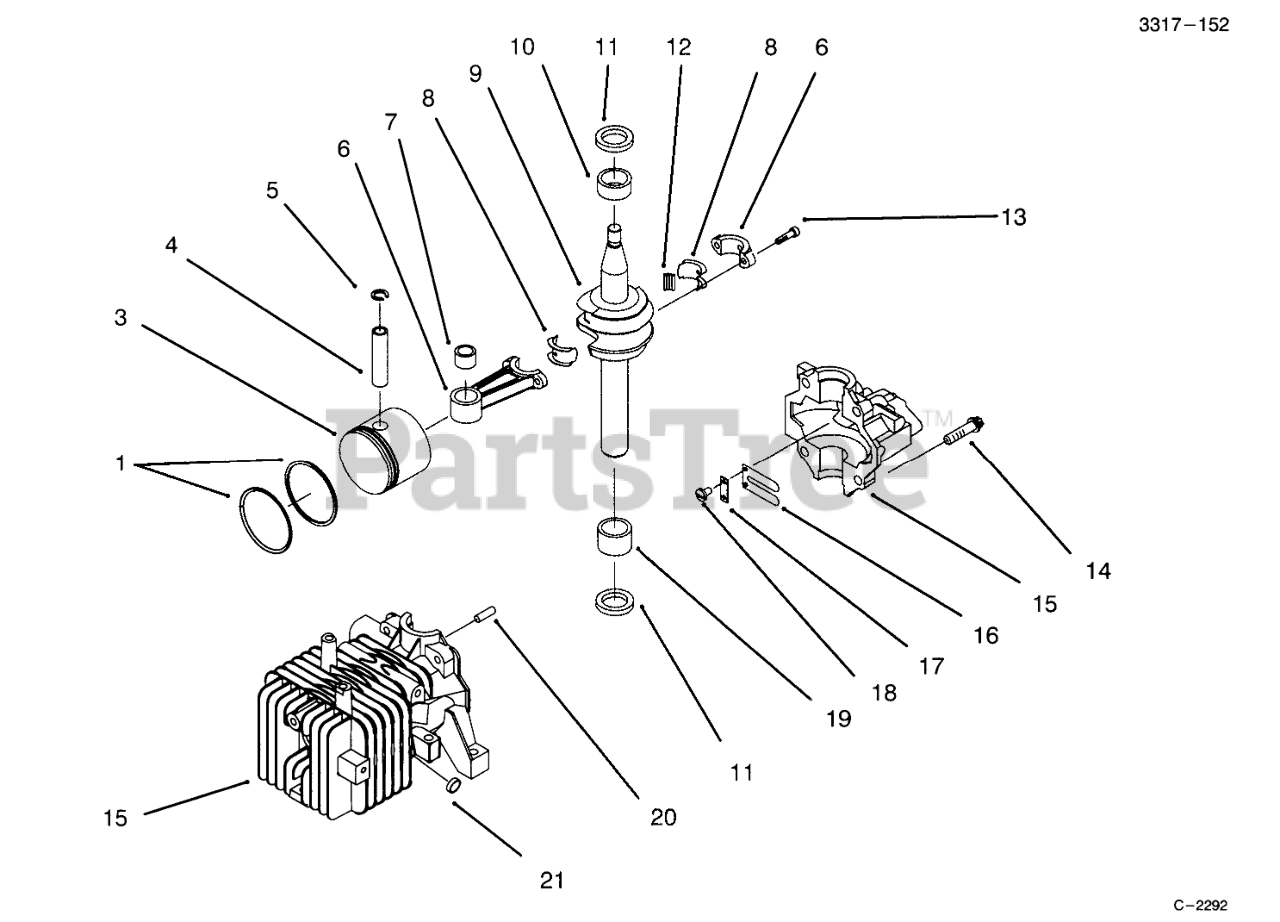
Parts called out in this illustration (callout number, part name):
1	F-RING SET
3	PISTON & RING
4	PIN-WRIST VF
5	RING-RETAINING
6	Connecting Rod Assembly (Incl Ref. #8,12,13)
7	BEARING XEV
8	LINER ASM
9	Crankshaft
10	BEARING V
11	SEAL-OIL
12	BEARING-NEEDLE
13	SCREW-HSH
14	SCREW-HWH V
15	Cylinder & Crankcase Cover (Incl Ref. #14,16,17,18,20,21)
16	REED-CARBURETOR
17	PLATE-BACKUP, REED
18	SCREW-HH
19	BEARING V
20	DOWEL XEV
21	PLUG-CORE VF
